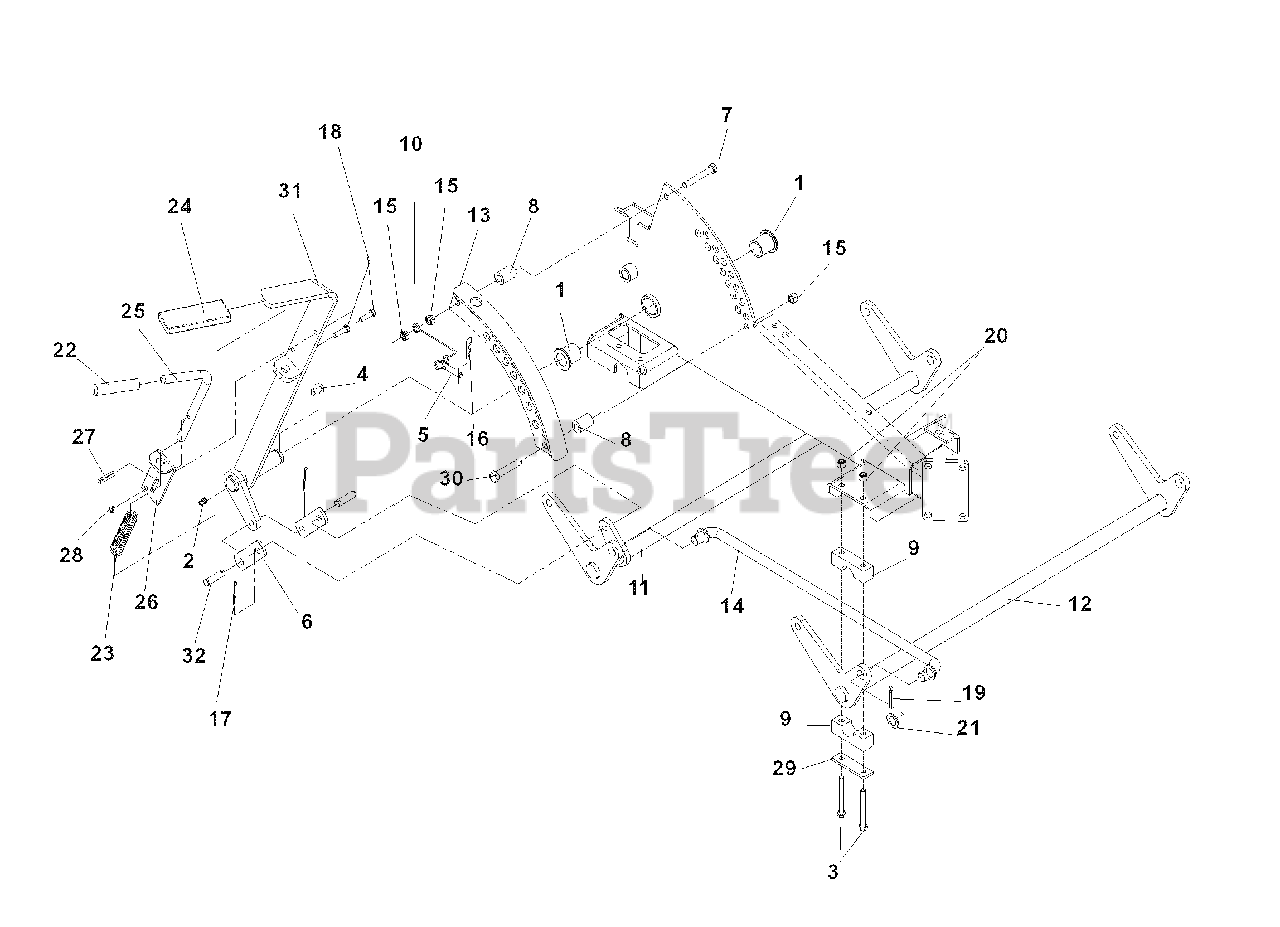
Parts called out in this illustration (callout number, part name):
3	HCS, 5/16 -18 x 2 3/4
4	RING-E, 7/ 8
5	PIN LIFT, 1/2 x 2, W/RINGS
7	HCS, 3/8 -16 x 2 3/4
9	BLOCK-PILLOW
11	REAR LIFT SHAFT
12	FRONT LIFT SHAFT
13	ADJUSTMENT PLATE
14	CROSS LINK
15	NUT, 3/8 -16, NYLOC
16	PIN HAIR, 120 x 2 1/2
17	PIN COTTER
18	HCS, 1/4 -20 x 3/4
19	PIN COTTER, 5/32 x 1 1/4
20	NUT, 5/16 -18, NYLOC
22	GRIP, VINYL
23	SPRING, COMPRESSION
24	GRIP, LIFT LEVER
25	PIN, 1/2 x 6.69 "L"
27	PIN GROOVED, 3/16 x 1 1/4
28	NUT, 1/4 -20, CENTERLOCK
29	REINFORCED BAR
30	HCS, 3/8 -16 x 2 1/2
31	LIFT LEVER
32	PIN CLEVIS, 3/8 x 1 1/8
